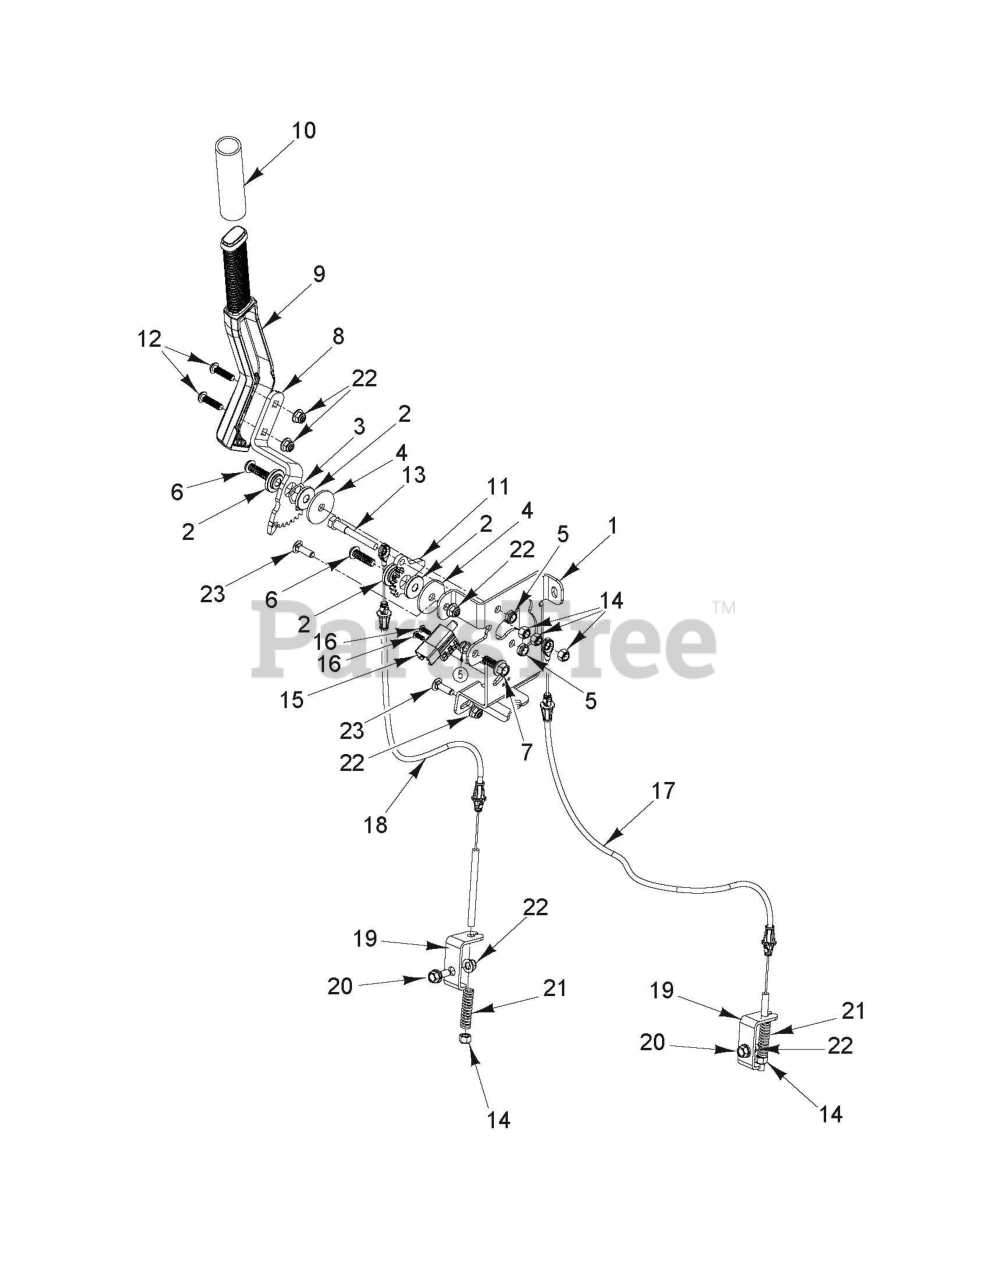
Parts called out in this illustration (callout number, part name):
1	BRACKET PARKING BRAKE;STAND ON
2	BUSHING, BRAKE
3	WASHER, .825 X 1.087, WAVE
4	Washers
5	Nuts
6	SCREW HEXALOBULAR SOCKET BUTTO
7	Screws
8	GEAR INPUT;PARKING BRAKE;STAND
9	LEVER PARKING BRAKE; STAND ON
10	GRIP PARKING BRAKE; STAND ON
11	GEAR OUTPUT;PARKING BRAKE;STAN
12	SCREW.BUTTHEAD.5/16-18X1-1.25
13	BOLT HEXAGON SHOULDER 5/16-18
14	Nuts
15	SWITCH INTERLOCKT
16	SCREW.BUTTONHD.10-24X1/2.(2 2)
17	CABLE PARKING BRAKE;STAND ON;L
18	CABLE PARKING BRAKE;STAND ON;R
19	Brackets
20	Bolts
21	SPRING PARKING BRAKE; STAND ON
22	NUT HEXAGON FLANGE 5/16-18 ST
23	Bolts
